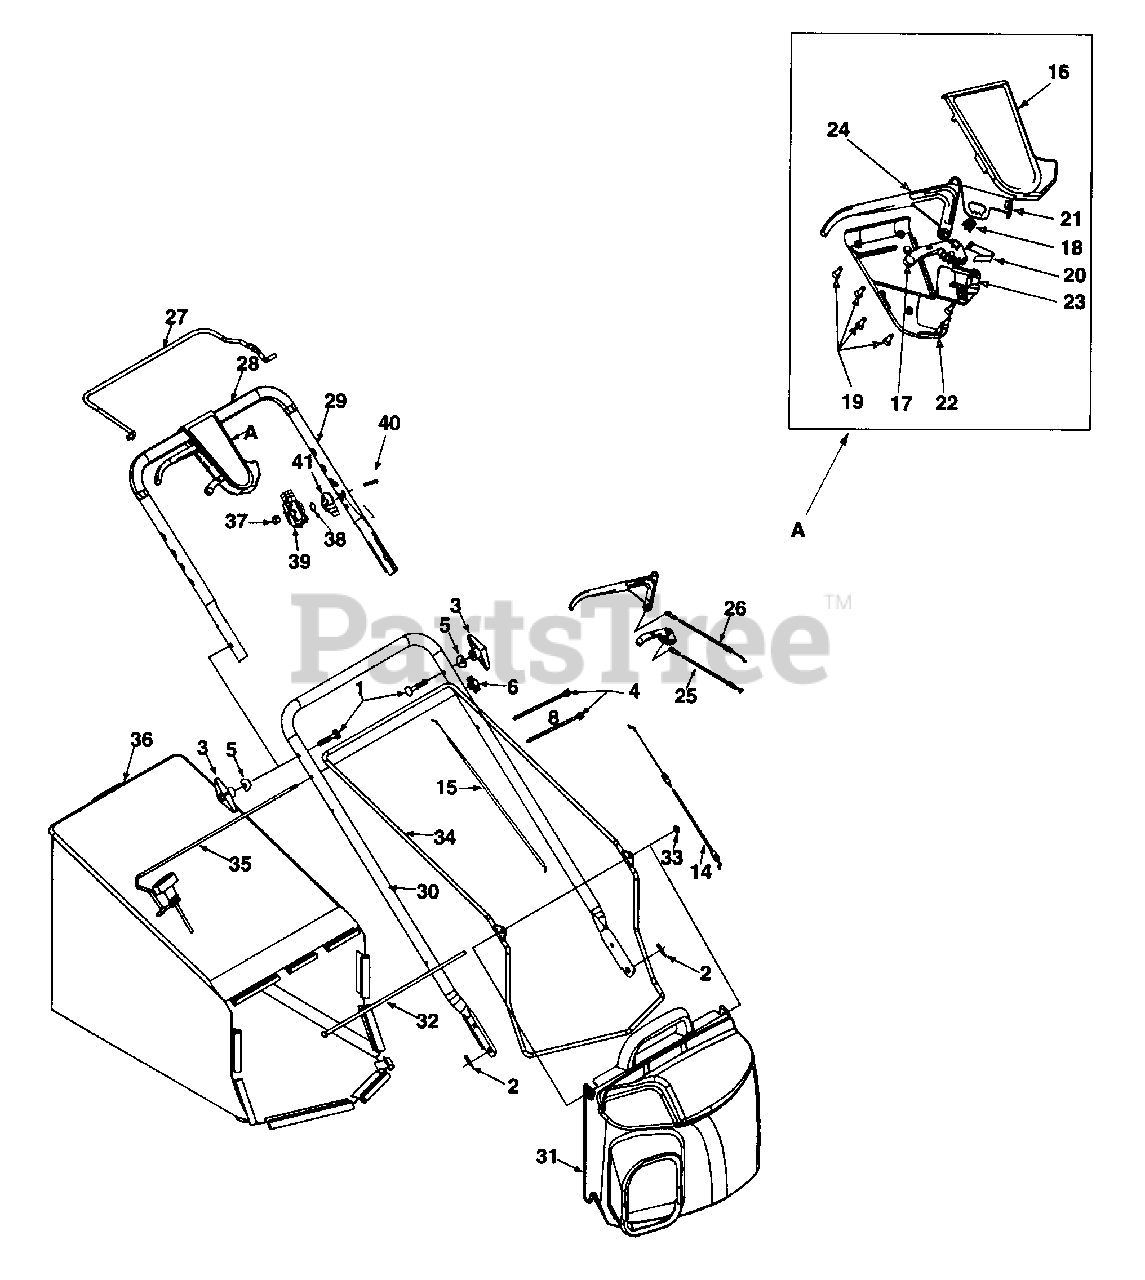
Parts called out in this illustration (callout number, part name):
1	Bolt Cur. Carr. 5/16-18 x 2.0
2	Cotter Pin .072 x 1.12 Lg.
3	Wingknob 5/16-18
4	Strap 4.3 Lg.
5	Wash. Sad. .320 ID x .830 OD
6	Handle Knob, 1/4-20
8	Screw 1/4-20 x 1.3
14	Control Cable 44" Lg.
15	Throttle Control 47" Lg.
16	Upper Control Housing
17	6 Speed Shift Lever
18	Gear Insert
19	C Sunk Tap Screw #10-16 x .625
20	Shift Lever Spring
21	6 Spd. Rack Cable Brkt.
22	Lower Control Housing
23	Cable Mounting Cap
24	Control Lever
25	6 Spd. Cable
26	Self Prop. Cable 52"
28	Foam Grip
31	Grassbag Cover w/Logo
32	Pivot Rod
33	Cap Nut
36	Grassbag
37	Hex Lock Nut, 1/4-20
38	Curved Wash. .663 x .980 x .014
39	Throttle/Choke Housing
40	Oval C-Sunk Screw 1/4-20 x 1.825
41	Throttle/Choke Lever
